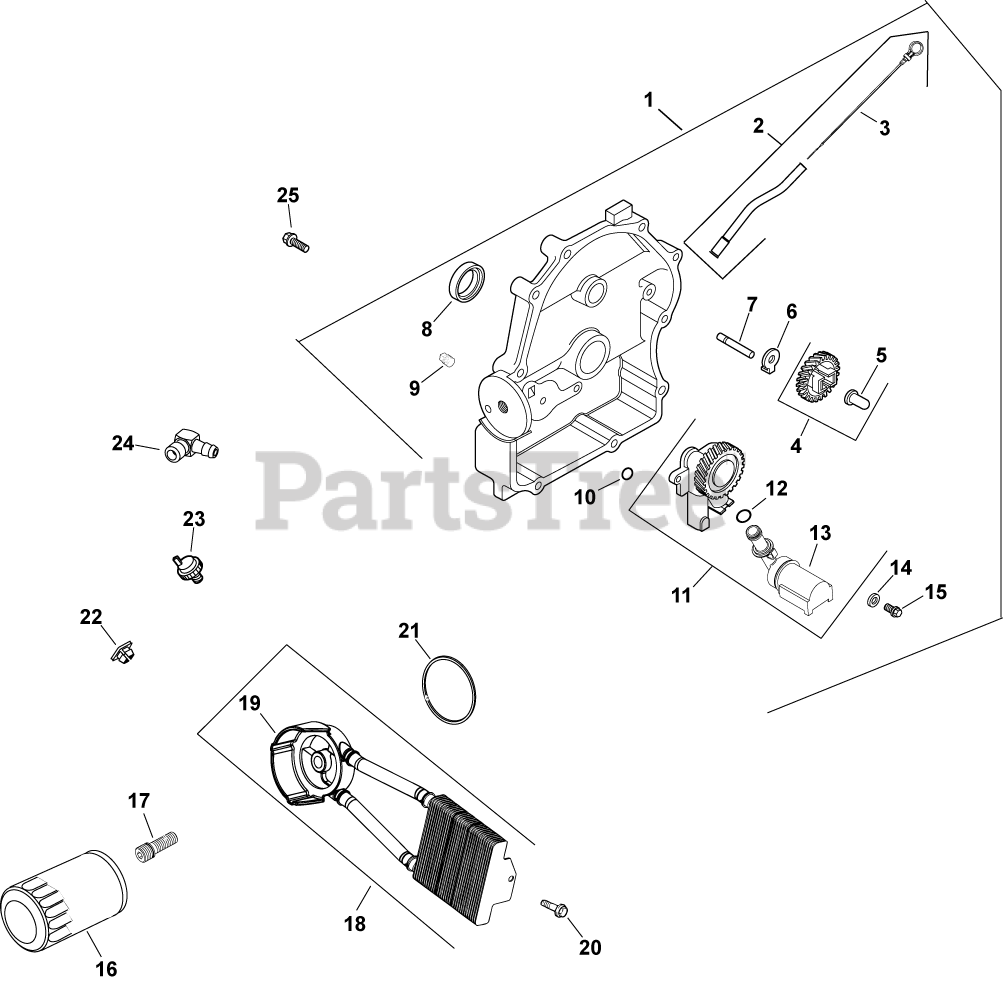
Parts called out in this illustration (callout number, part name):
1	CLOSURE PLATE ASSEMBLY USE 24 009 215-S
2	KIT, DIPSTICK/DIPSTICK TUBES
4	KIT, GOVERNOR GEAR W/PIN
5	KIT, GOVERNOR GEAR W/PIN
6	TAB, LOCKING
7	SHAFT, GOVERNOR GEAR
8	SEAL, OIL (KM)-USE 25 032 06-S
9	PLUG, CTSK PIPE 1/8"
11	PUMP ASSEMBLY, OIL-USE 24 393 53-S
12	O-RING, OIL PICK-UP
13	PICK-UP, OIL
14	WASHER, FLAT 6 MM
15	SCREW,FLG THD FRM M6X1.0X25-(#25086395S)
16	OIL FILTER
17	NIPPLE, OIL FILTER
18	COOLER, OIL - PHENOLIC-USE 24 594 36-S
19	ADAPTER, OIL FILTER-USE 24 029 75-S
20	SCREW, TAP M6X1.7X18
21	O-RING, OIL COOLER
22	NUT, PLASTIC (KM)-USE 25 100 37-S
23	SENSOR, OIL PSI
24	CONNECTOR, 90 DEG. HOSE
25	SCREW, FLG M8X1.25X45
